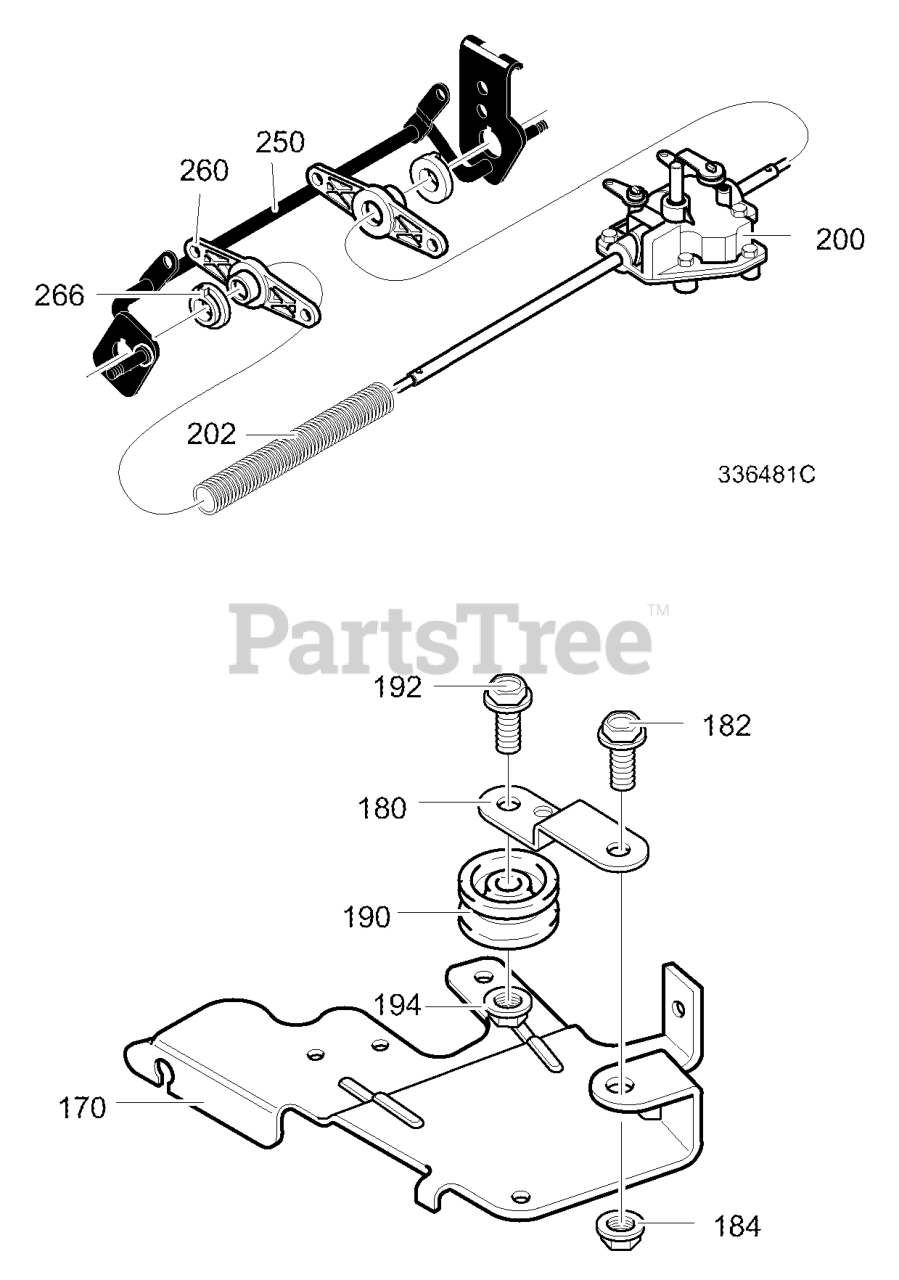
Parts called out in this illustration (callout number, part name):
170	Bracket
180	Idler, Arm
182	Bolt, HHSH 3/8-16
184	Nut, 3/8-16
190	Pulley, Idler
192	Screw, 5/16-18 x 1.13
194	Nut, 5/16-18
200	Transmission 3 Speed
202	Shield, Axle
250	Crossbar Assy., Rear
260	Support, Axle w/bring
266	Bearing, Lifter
